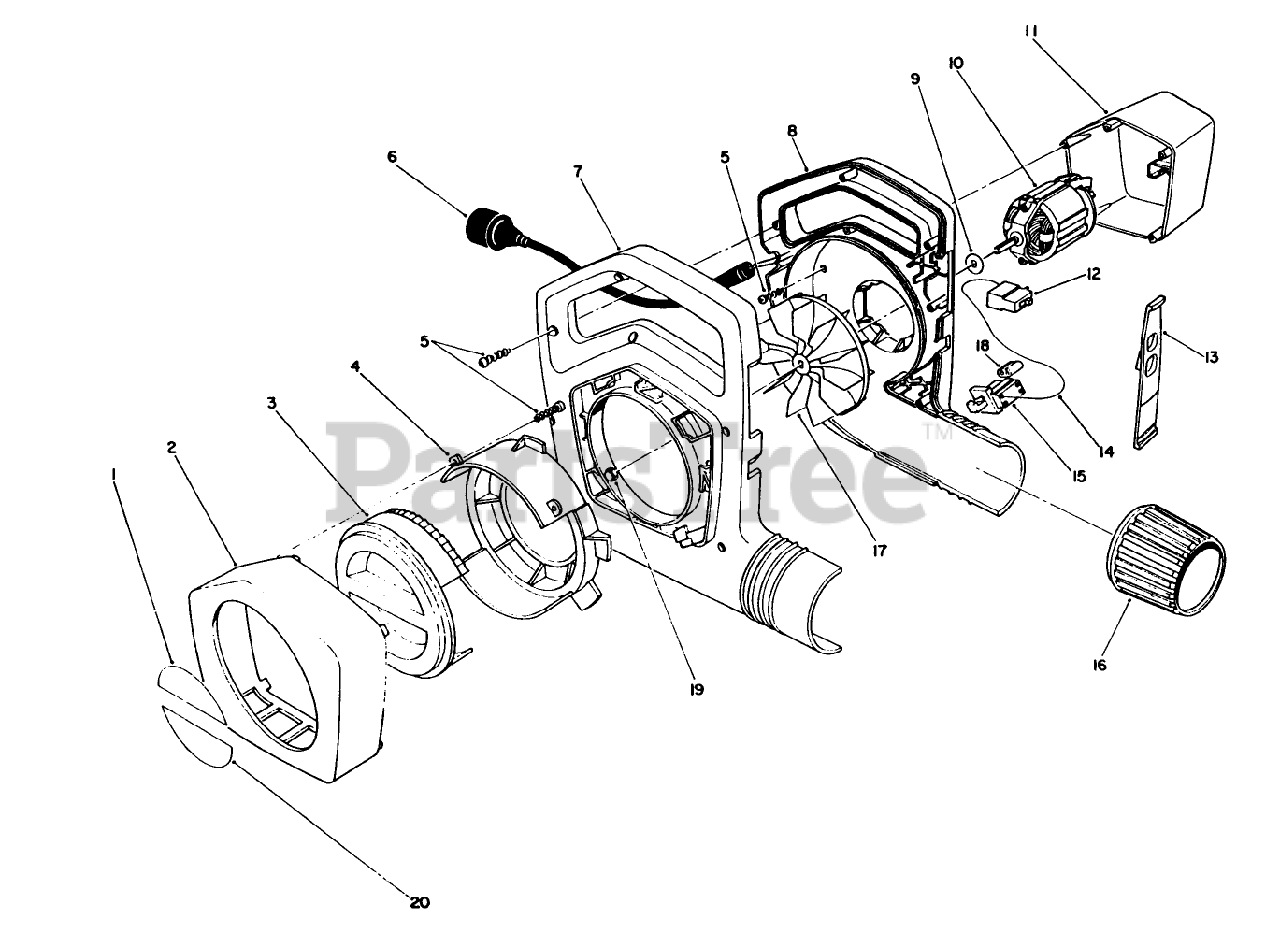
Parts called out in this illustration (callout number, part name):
1	Decal-Upper Choke (Model No. 51535)
1	DECAL, UPPER CHOKE, 550
2	BV-TRIM RING WH RED
3	BV CH ADJUSTER WH RED
4	Ring-Tab
5	Screw
6	POWER SUPPLY CORD,9.5"
7	Housing-Blower, R.H.
8	Housing-L.H.
9	Washer-Impeller
10	MOTOR, BLOWER (450/550)
11	Cover-Motor
12	Switch-On/Off
13	Cam-Switch-On/Off
14	WIRE -INTERNAL
15	SWITCH-INTERLOCK
16	Collar-Output
17	IMPELLER-NEW STYLE
18	NEW STYLE DUST PLUG
19	NUT-LOCK, CAP
20	DECAL, LOWER CHOKE, 450
20	DECAL, LOWER CHOKE, 550
